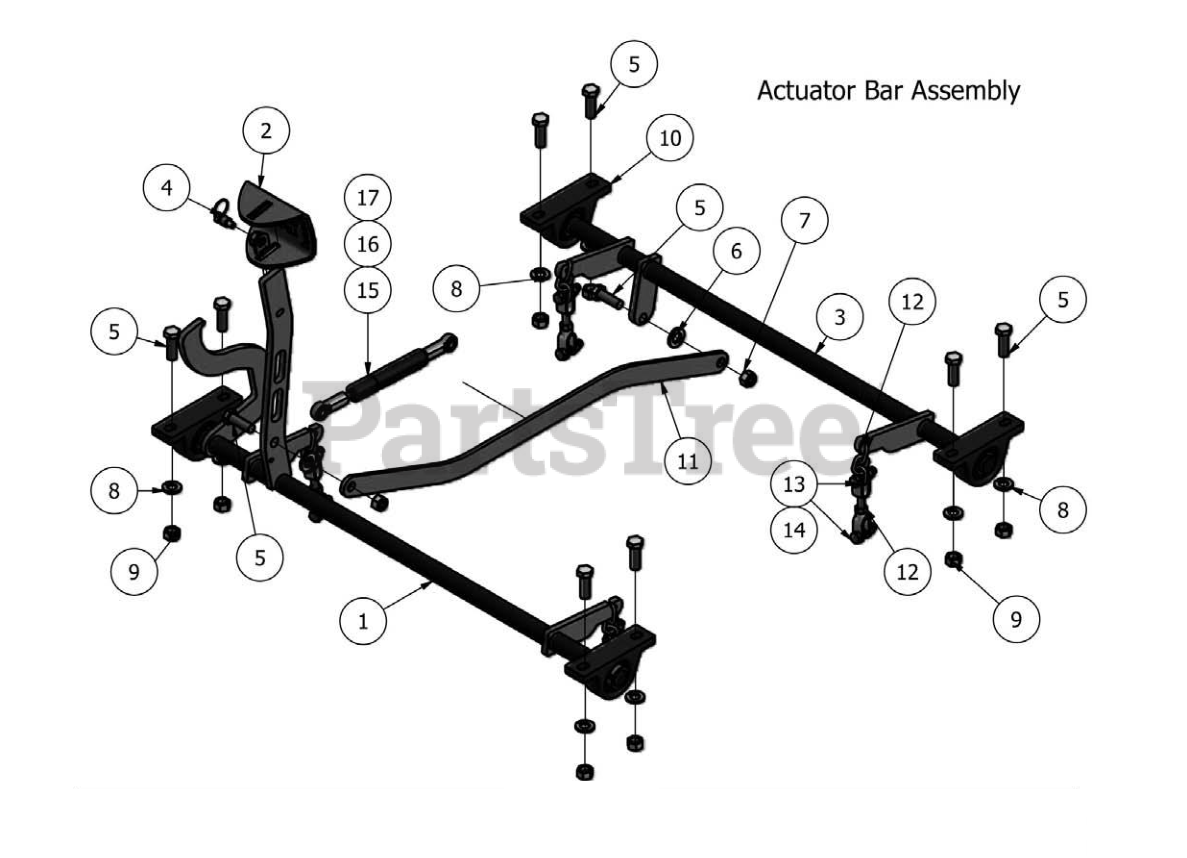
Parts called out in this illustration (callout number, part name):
1	Outlaw Actuator Bar Assembly Front
2	Deck Assist- Foot Petal
3	Outlaw Actuator Bar Assembly Rear
5	1/2-20 x 1-1/2 Grade 5 Hex Bolt Zinc
6	.630 ID X 1.122 OD X .142 THK Flat Washer Nylon
7	1/2-12 Nylon Locknut Zinc Orange Nylon
8	1/2 Lock Washer Zinc
9	1/2-13 Hex Nuts Zinc
10	Pillow block 2bolt sealmaster
11	Outlaw Deck Linkage Rod
12	Yoke/Deck Hanger Assby - 2 Link Chain
13	3/8-16 x 1/ 1/2 GR5 Hex Bolt
14	3/8-18 Nylon Insert Locknut Zinc Orange Nylon
15	Damper For 72"
16	Damper for 61"
17	Damper for 54"
